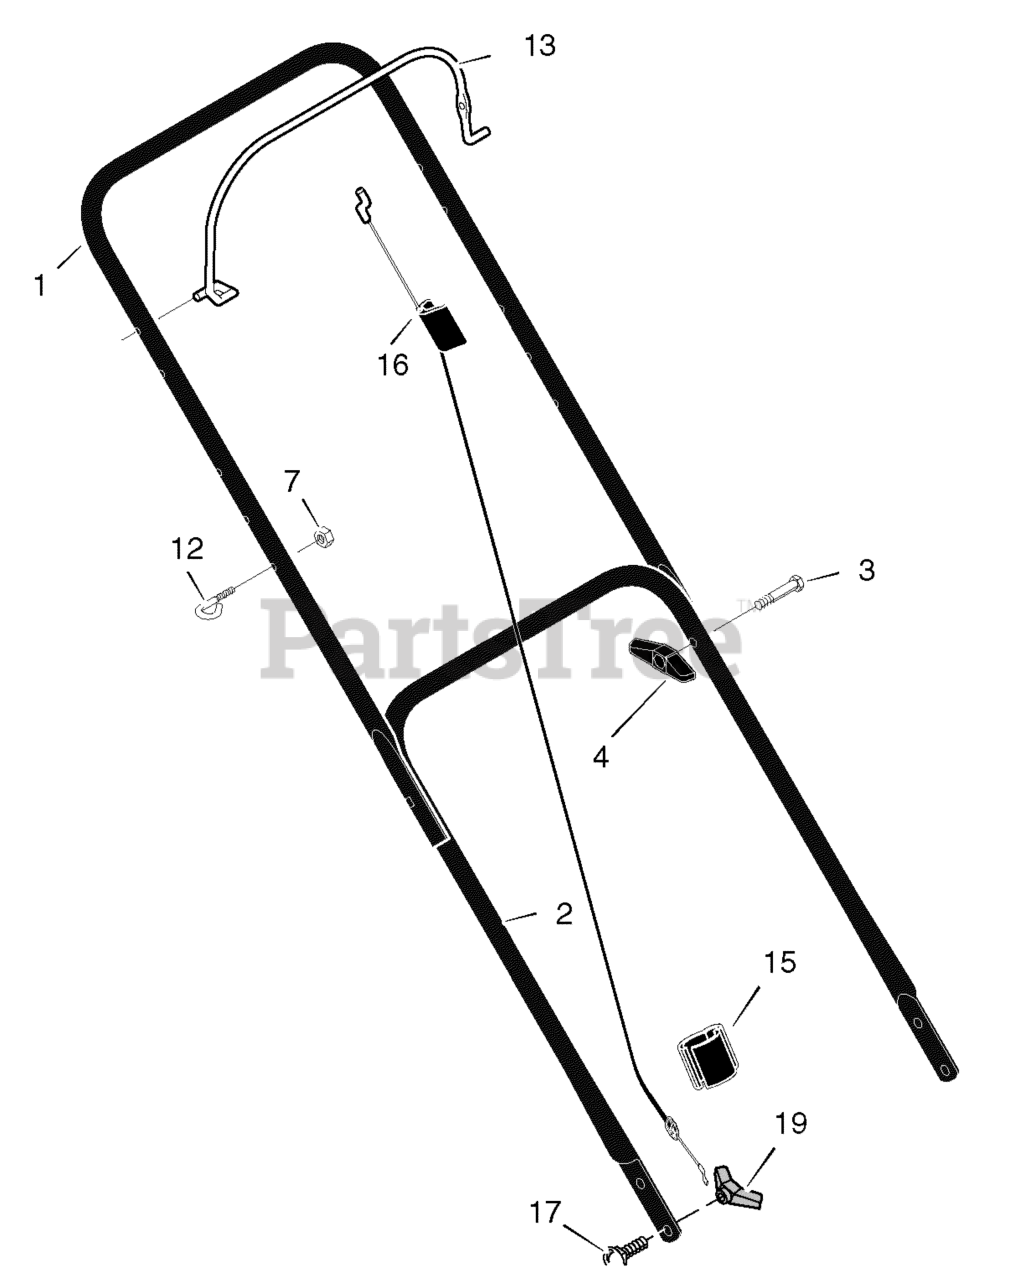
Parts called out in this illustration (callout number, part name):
1	Handle, Upper (Black)
1	Handle, Upper (Gray)
2	Handle, Lower (Black)
2	Handle, Lower (Gray)
4	Knob, Plastic
7	Locknut
12	Guide, Rope
13	Lever, Engine Stop
15	Clip, Cable
16	Engine Stop Cable
17	Bolt, Carriage
19	Knob, Plastic
